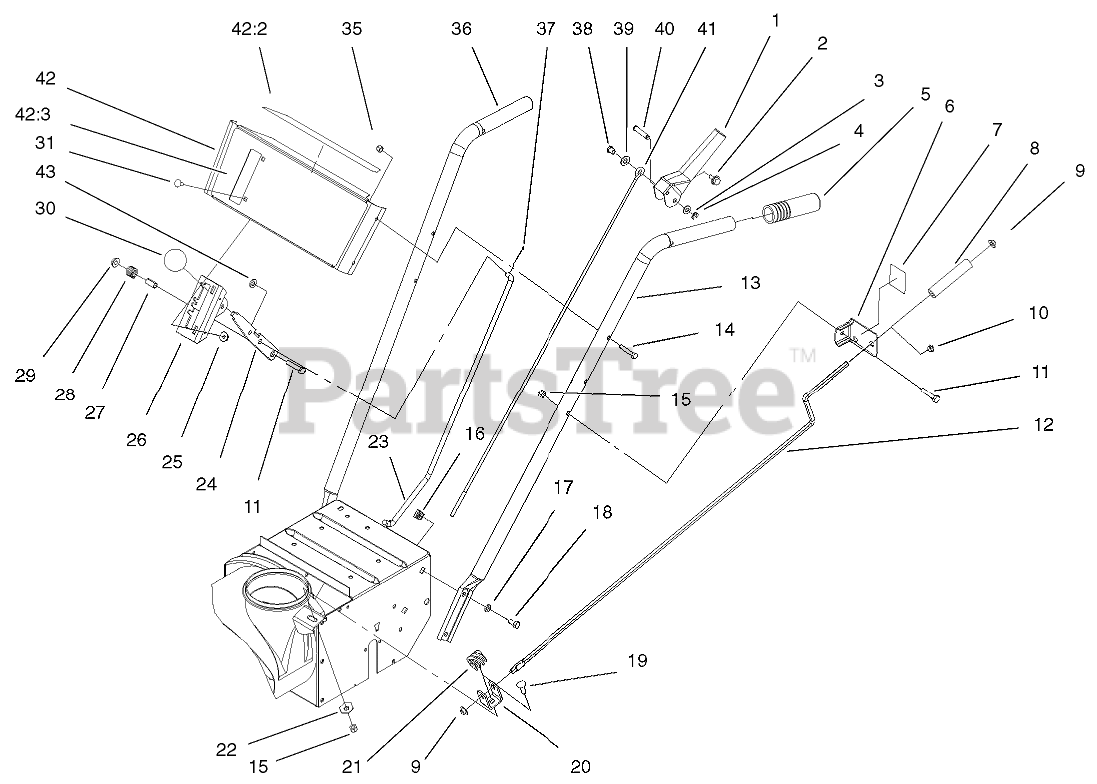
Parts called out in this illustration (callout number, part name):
1	HANDLE-CONTROL
2	SCREW-HHF
3	WASHER-PLAIN
4	RING-CLIP
5	GRIP-HANDLE
6	BRACKET-ROD, CHUTE
7	DECAL-CHUTE DIRECTION
8	GRIP-CONTROL, CHUTE
9	RETAINER-PUSH ON
10	Bushing
11	SCREW-HH
12	ROD-CONTROL, CHUTE
13	HANDLE-LEFT
14	SCREW-HH
15	NUT-LOCK, NI
17	WASHER-BELLEVILLE
18	SCREW-HH
19	SCREW-CARR
20	BRACKET-WORM
21	GEAR-WORM, CHUTE
22	WASHER-LOCK
23	ROD-SELECTOR, SPEED
24	SELECTOR-SPEED
25	NUT-HF
26	MOUNT-SELECTOR, SPEED
27	SPACER
28	SPRING
29	NUT-HF
31	SCREW-CARR
35	NUT-LOCK, NI
36	HANDLE-RIGHT
37	PIN-COTTER
38	POST-MOUNTING, LINKAGE
39	WASHER-FLAT
40	PIN-LEVER, CONTROL
41	LINK-UPPER
42	Panel ASM Service] (only on: 38064)
42	Panel ASM (only on: 38063)
42:2	Decal-Escutcheon Back (only on: 38063)
42:2	Decal-Escutheon Back (only on: 38064)
42:3	Decal-Escutcheon (only on: 38064)
42:3	Decal-, Escutcheon (only on: 38063)
43	WASHER-FLAT
